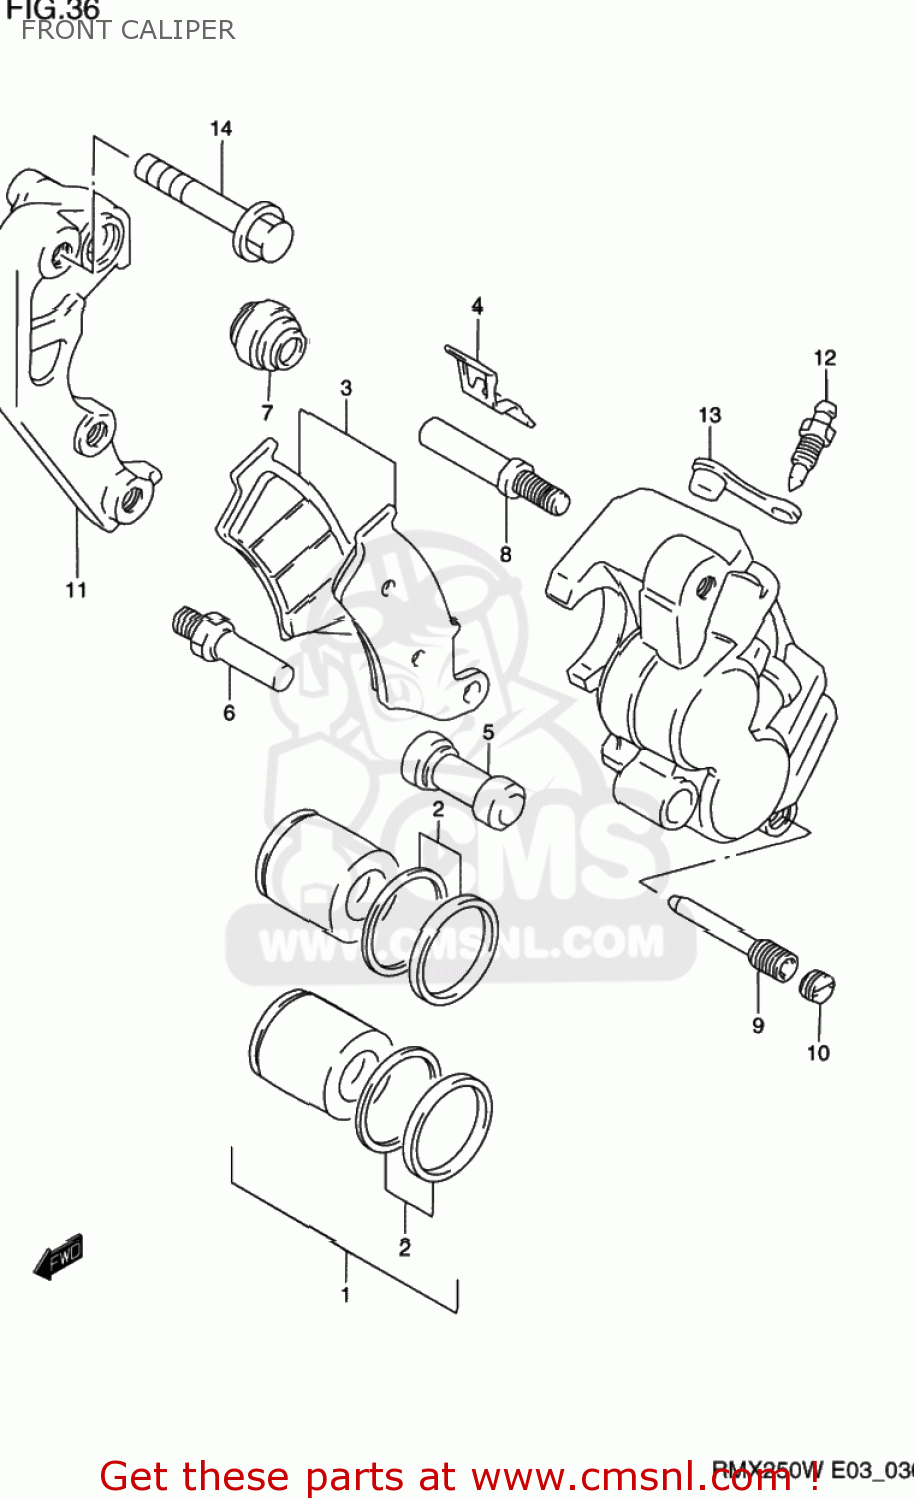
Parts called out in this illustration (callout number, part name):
1	PISTON SET
2	SEAL SET,PISTON
3	PAD SET (NAS)
4	SPRING,PAD
5	BOOT
6	PIN,BOLT
7	BOOT
8	PIN
9	PIN,HANGER
10	PLUG,PIN
11	BRACKET
12	BLEEDER
13	CAP,BLEEDER
14	BOLT(8X40)
